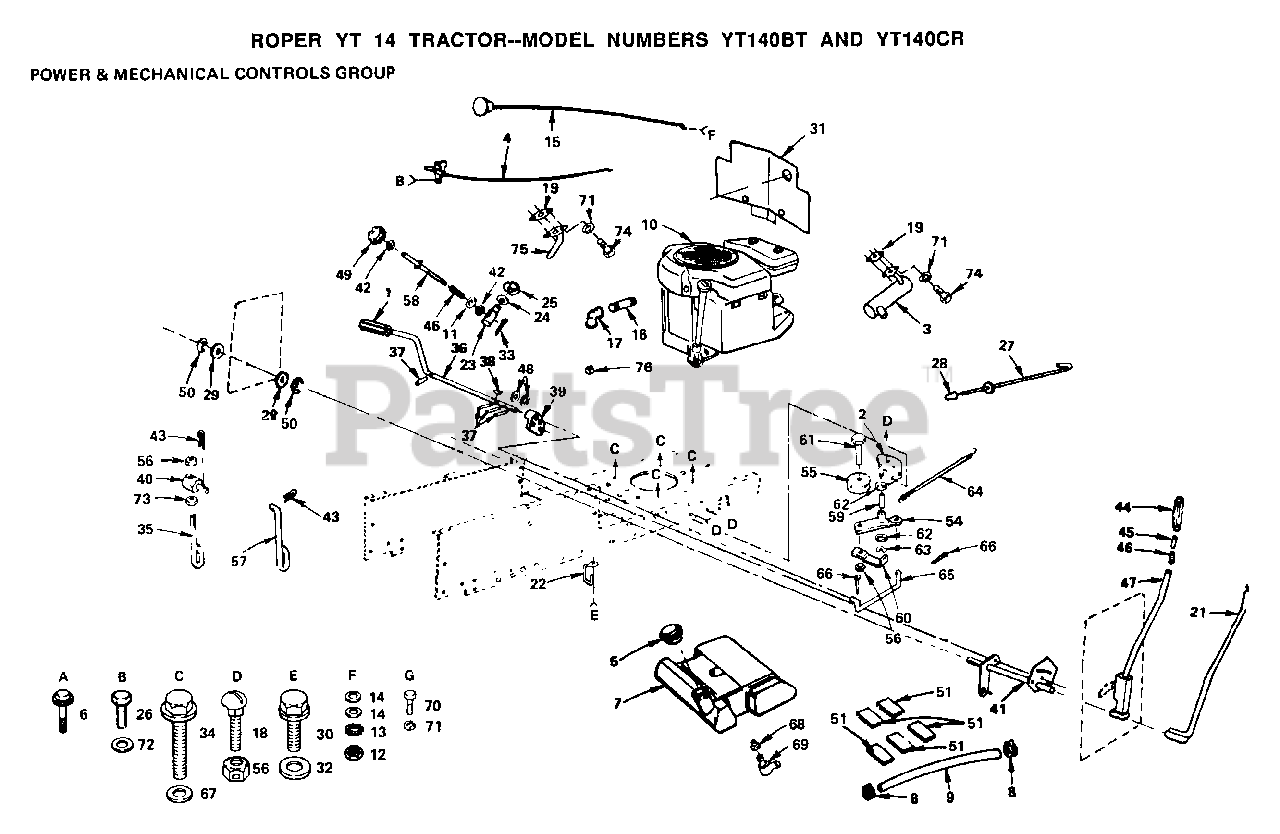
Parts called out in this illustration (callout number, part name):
1	PEDAL COVER T
11	WASHER
13	LOCKWASHER
14	WASHER
16	PIPE NIPPLE LT
17	ELBOW
18	BOLT
21	LEVER ROD LT
23	TRUNION LT
24	WASHER
25	KLIP RING
26	SCREW
28	PLUNGER CAP T
29	WASHER
30	SCREW
32	WASHER
34	SCREW LT
35	LINK LIFT LT
36	No Desciption for Part
39	ARM BRAKE LT
41	No Desciption for Part
42	NUT T
44	GRIP
46	SPRING T
50	E-RING
51	PAD-SPACER T
57	LIFT LINK LT
58	ROD LIFT LT
59	"LY, BEARING"
62	WASHER LT
63	KLIP RING
64	"SPRING, RETURN LT"
65	"LINK, CLUTCH T"
66	COTTER PIN
67	WASHER
68	BUSHING OUTLET T
69	FUEL TANK STEM GT
70	BOLT
71	LOCKWASHER
72	WASHER
73	NUT.HEX.3/8-16UNC
75	EXHAUST TUBE T
76	PLUG OIL DRAIN
